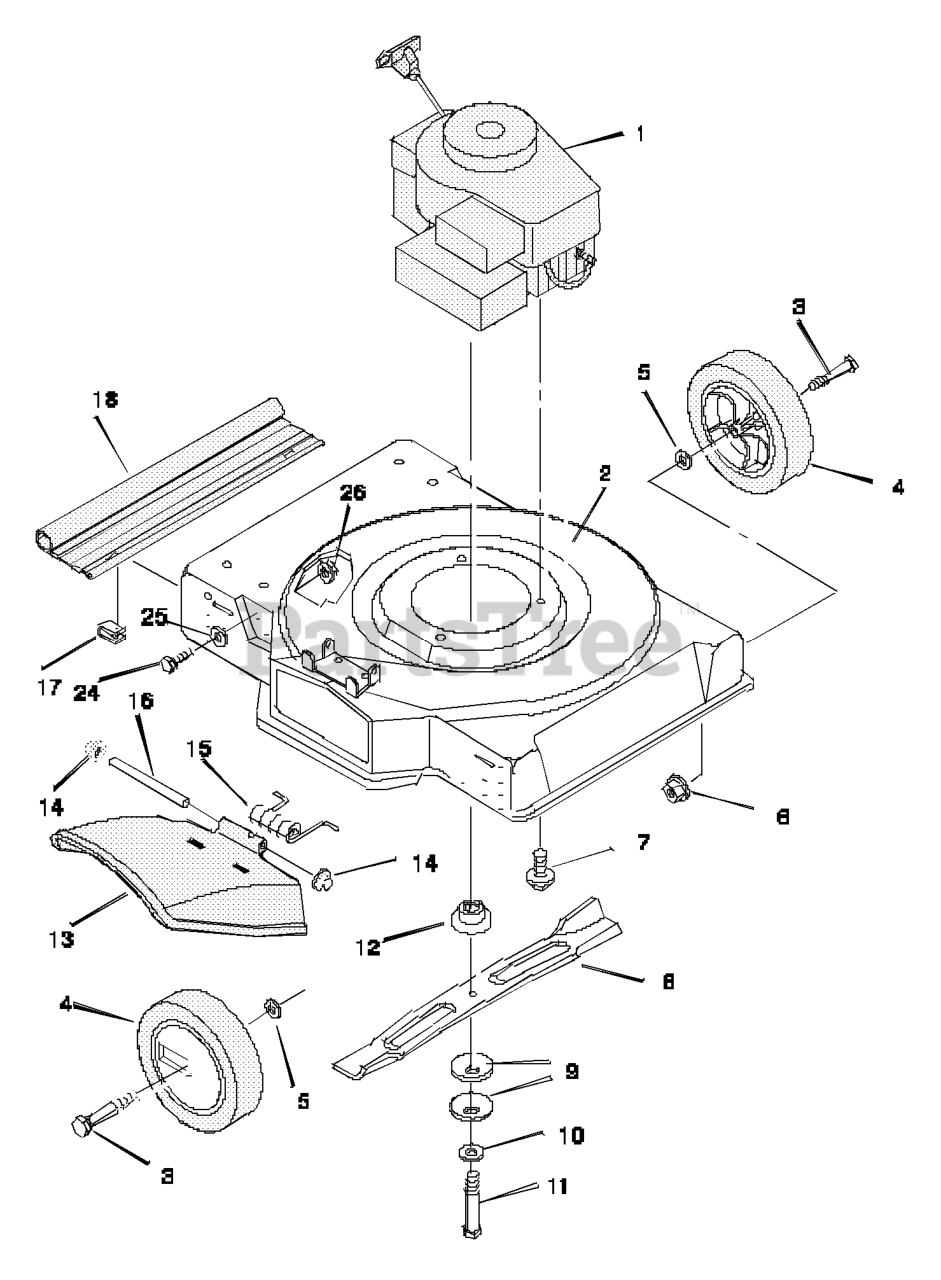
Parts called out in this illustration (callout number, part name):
1	Engine *
2	Housing,
3	Bolt, Axle
4	Wheel and Tire
6	Locknut, Flange
7	Bolt, Engine
9	Washer, Belleville
11	Bolt, Hex
12	Adapter, Blade
13	Deflector, Chute
14	Push- On Cap
16	Pin, Pivot
17	Retainer
18	Deflector, Rear
24	Bolt, Hex
26	Locknut, Flange
